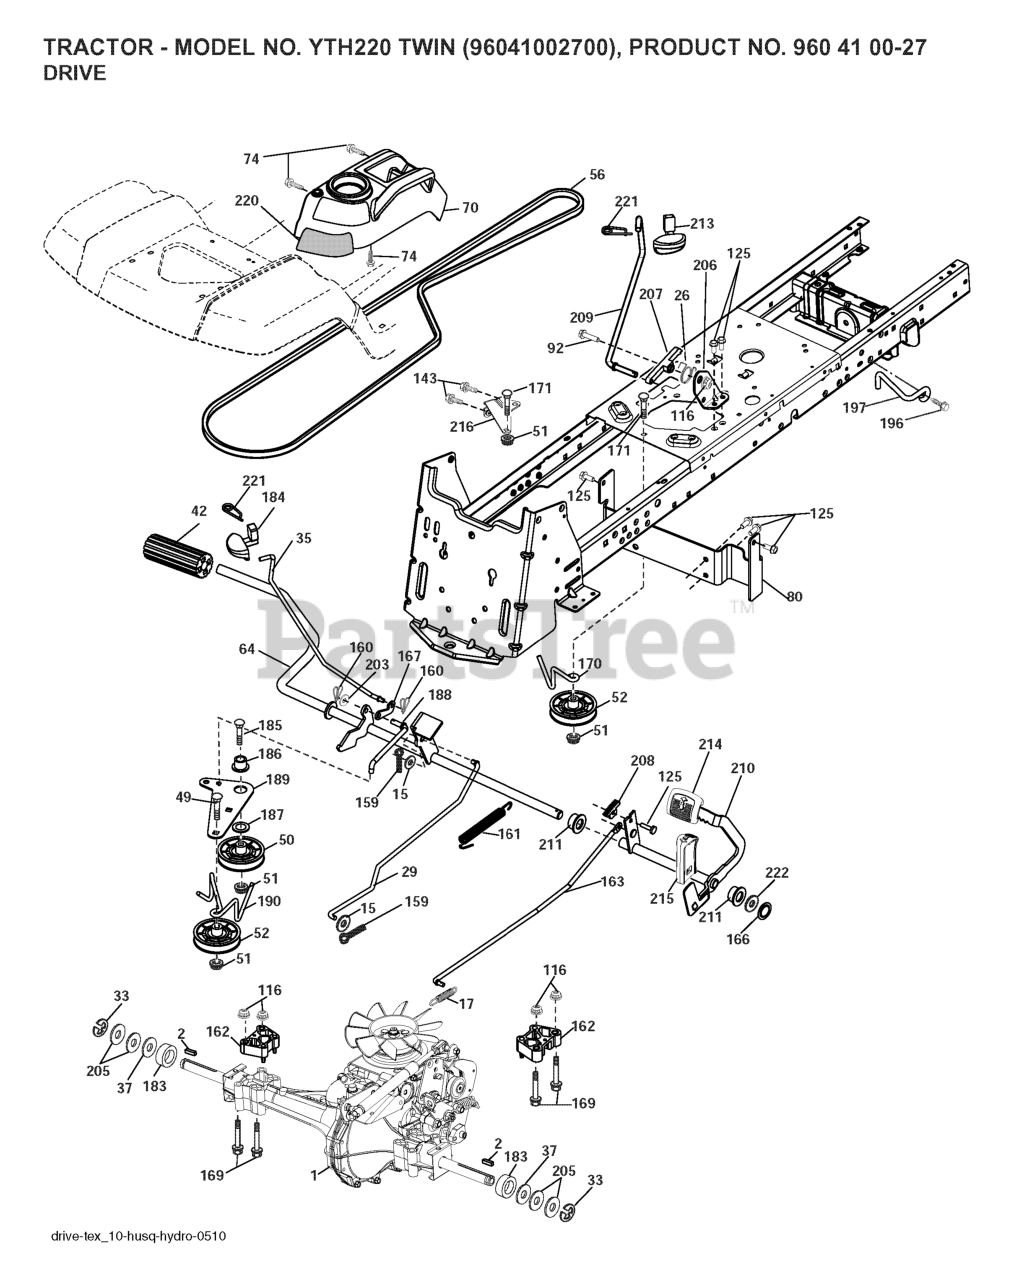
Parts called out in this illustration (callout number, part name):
15	WASHER
17	SPRING.BRAKE.HG3000/3500
26	SPRING.RETURN.CRUISE
29	ROD.BRAKE.0610.PEDAL.CONTROL
35	ROD.BRAKE.PARKING.GT.H
42	PEDAL COVER T
50	IDLER.FLAT.910.OFFSET
51	NUT LOCK FLG 3/8-16 UNC
52	IDLER.V-GROOVE.910.OFFSET
64	SHAFT.ASM.PEDAL.BRK.CNTR
70	RP CONSOLE.ASM.PCH.W/TB
74	SCREW.HI-LO.CONSOLE
80	BRKT.STRP.TRQ.LT.HYD.C
92	BOLT
116	NUT LOCK HEX FLANGE 5/16-18
125	SCREW
143	Screw 5/16-18 x 1/2 Hex, Self Tapping 5/16-18 x 1/2
159	COTTER PIN
160	RETAINER CLIP
161	SPRING.RETURN.CLUTCH.2006
162	SPACER.TRANSAXLE.18&22
163	ROD.PEDAL.CONTROL.0510
166	NUT.PUSH.625.2006
167	LATCH.BRAKE.SPRING
169	BOLT.HEX.FLNG.5/16-18X3.75
170	KEEPER.V-IDLER.CENTER.
183	SPACER.SPLIT.800X.350
184	HANDLE.PARKG.BRK.HUSQ X667
186	SPACER.RETAINER
187	WASHER 12/32X2X10GA
188	RP.LINK.CLUTCH.GROUND.DRIVE
189	BELLCRANK.GROUND.DRIVE.TEX.
190	KEEPER.BELLCRANK.DRIVE
196	SCREW 3/8-16X1
197	BRKT.ANIT-ROTATION.CLUTCH
203	WASHER
206	BRKT.MOUNT.LATCH.CRUIS
207	LATCH.CONTROL.CRUISE
208	GEAR.SECTOR.CONTROL.CR
209	ROD.CONTROL.CRUISE.GT.
210	ROCKER.ASM.PEDAL.CONTR
211	BEARING.NYLON
213	KNOB.CONTROL.CRUSIE.HU
214	PEDAL.FORWARD.TEX.GT.4
215	PEDAL.REVERSE.TEX.GT.4
216	BRACKET.PULLEY.IDLER.W/TEX
220	REFLECTOR.RH.TEX GT
221	RETAINER.SPRING.CLIP.H
222	WASHER 21/32 X 1-1/4 X 10 GA.
